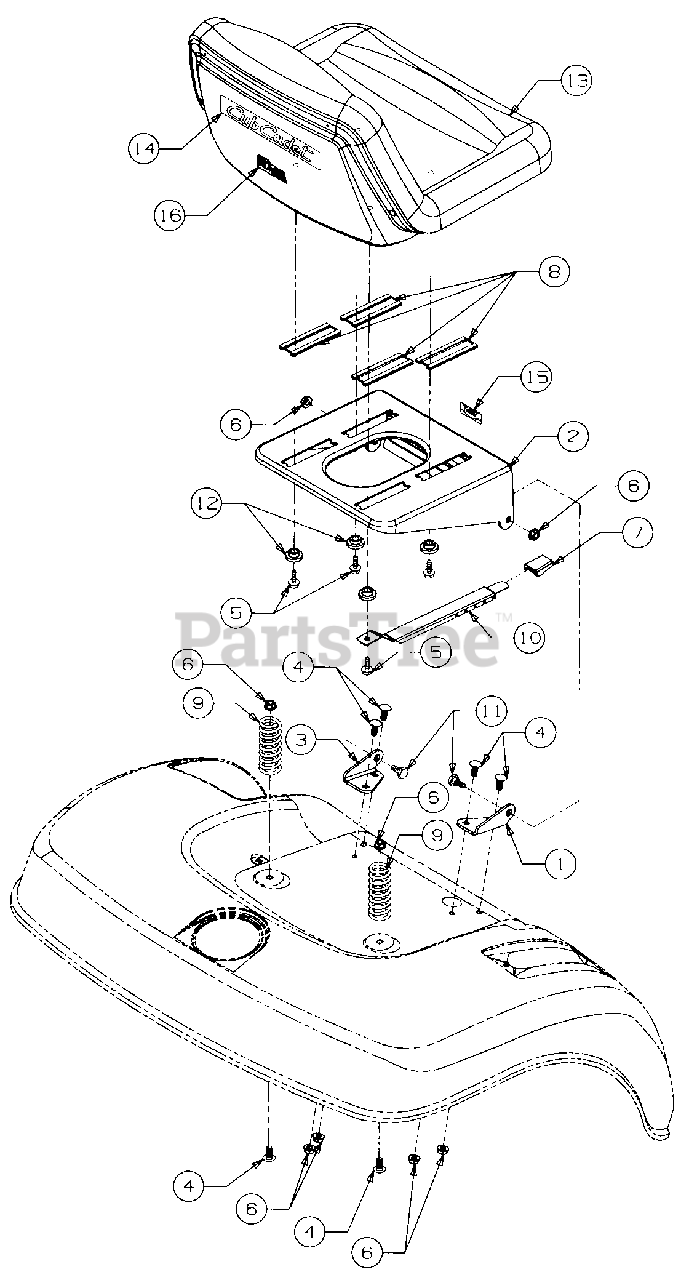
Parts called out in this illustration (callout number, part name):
5	Screw, Hex Wsh Hd Tap, 5-16-18 x .75
6	Nut, Hex Flange Lock, 5/16-18
7	Knob, Seat Adjuster
8	Slide, Seat
9	Spring, Compression, 1.9 OD x 2.4 Lg
10	Adjuster, Seat
11	Bolt, Shoulder
12	Spacer, Shoulder
13	Seat, Medium Back
14	Graphic, Seat Back
15	Graphic, Seat Adjuster
16	Graphic, Made in USA
